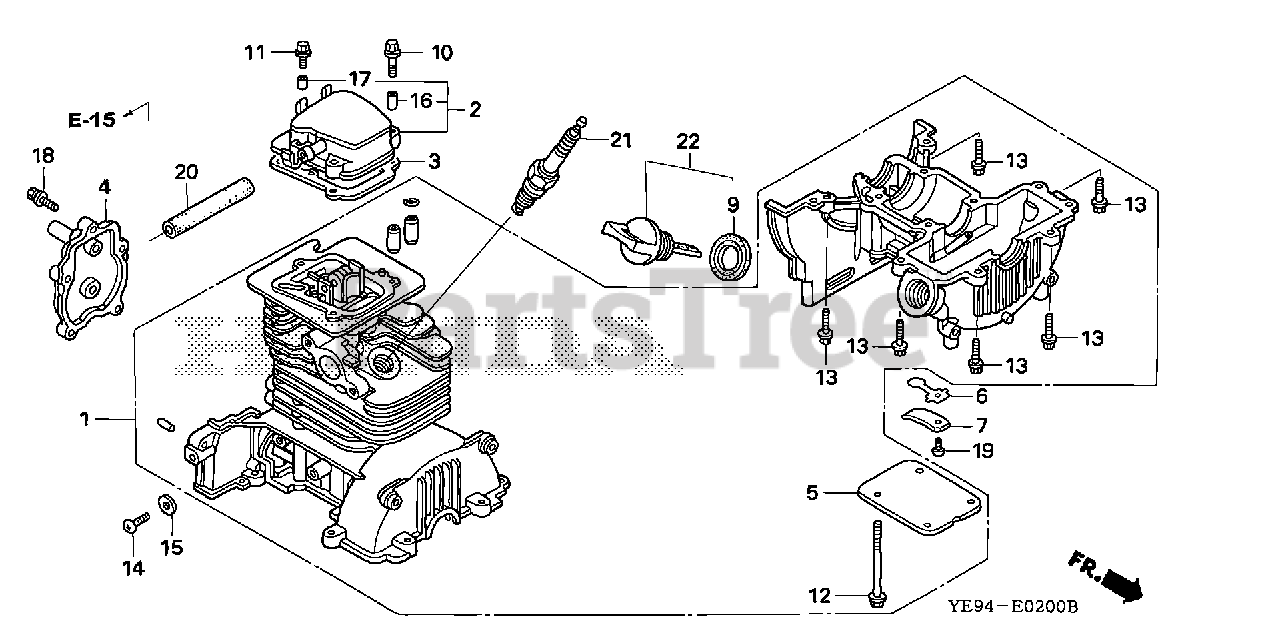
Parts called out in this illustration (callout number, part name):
1	CRANKCASE SET
2	COVER, HEAD
3	GASKET, HEAD COVER
4	COVER, CAMSHAFT
5	COVER, OIL OUTLET VALVE
6	VALVE, OIL OUTLET
7	PLATE, STOPPER
9	GASKET, OIL FILLER CAP
10	BOLT, FLANGE (5X22)
11	BOLT, FLANGE (5X14)
12	BOLT, FLANGE (5X55)
13	BOLT, FLANGE (5X18)
14	SCREW, PAN (6X8)
15	WASHER, SEALING (6.5MM)
16	COLLAR, HEAD COVER
17	COLLAR A, HEAD COVER
18	BOLT-WASHER (4X16)
19	SCREW, PAN (3X5)
20	BULK HOSE, VACUUM (7X3000) (7X68)
21	SPARK PLUG (CR5HSB)
22	CAP ASSY., OIL FILLER
